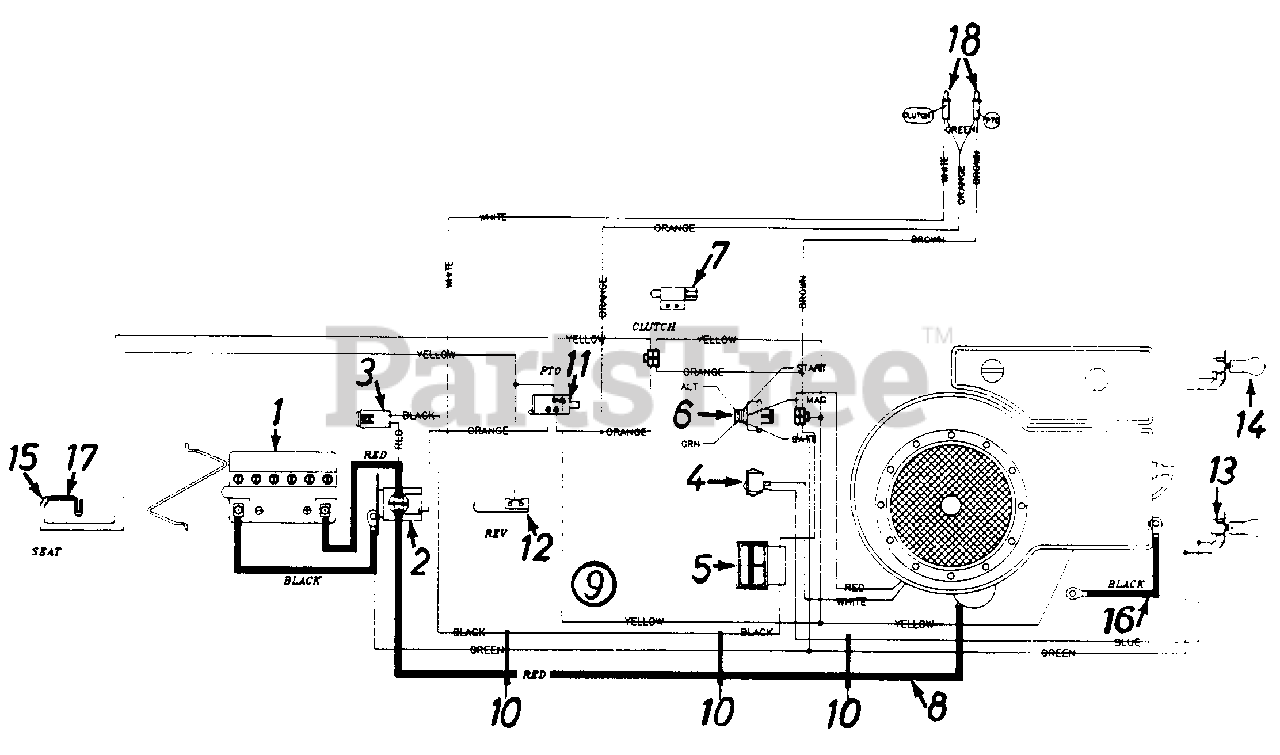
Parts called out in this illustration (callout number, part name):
1	Battery
2	Solenoid
3	Fuse 7.5 Amps
4	Light Switch
5	Ammeter
6	Ignition Switch
7	Safety Switch
8	Electric Wire 30" Lg.
9	Wire Harness
11	Safety Switch (Deck)
12	Safety Switch (Reverse)
13	Socket
14	Bulb (Headlight)
15	Safety Switch (Seat)
16	Ground Wire 7.5" Lg.
17	Safety Switch (Seat)
18	Bulb
